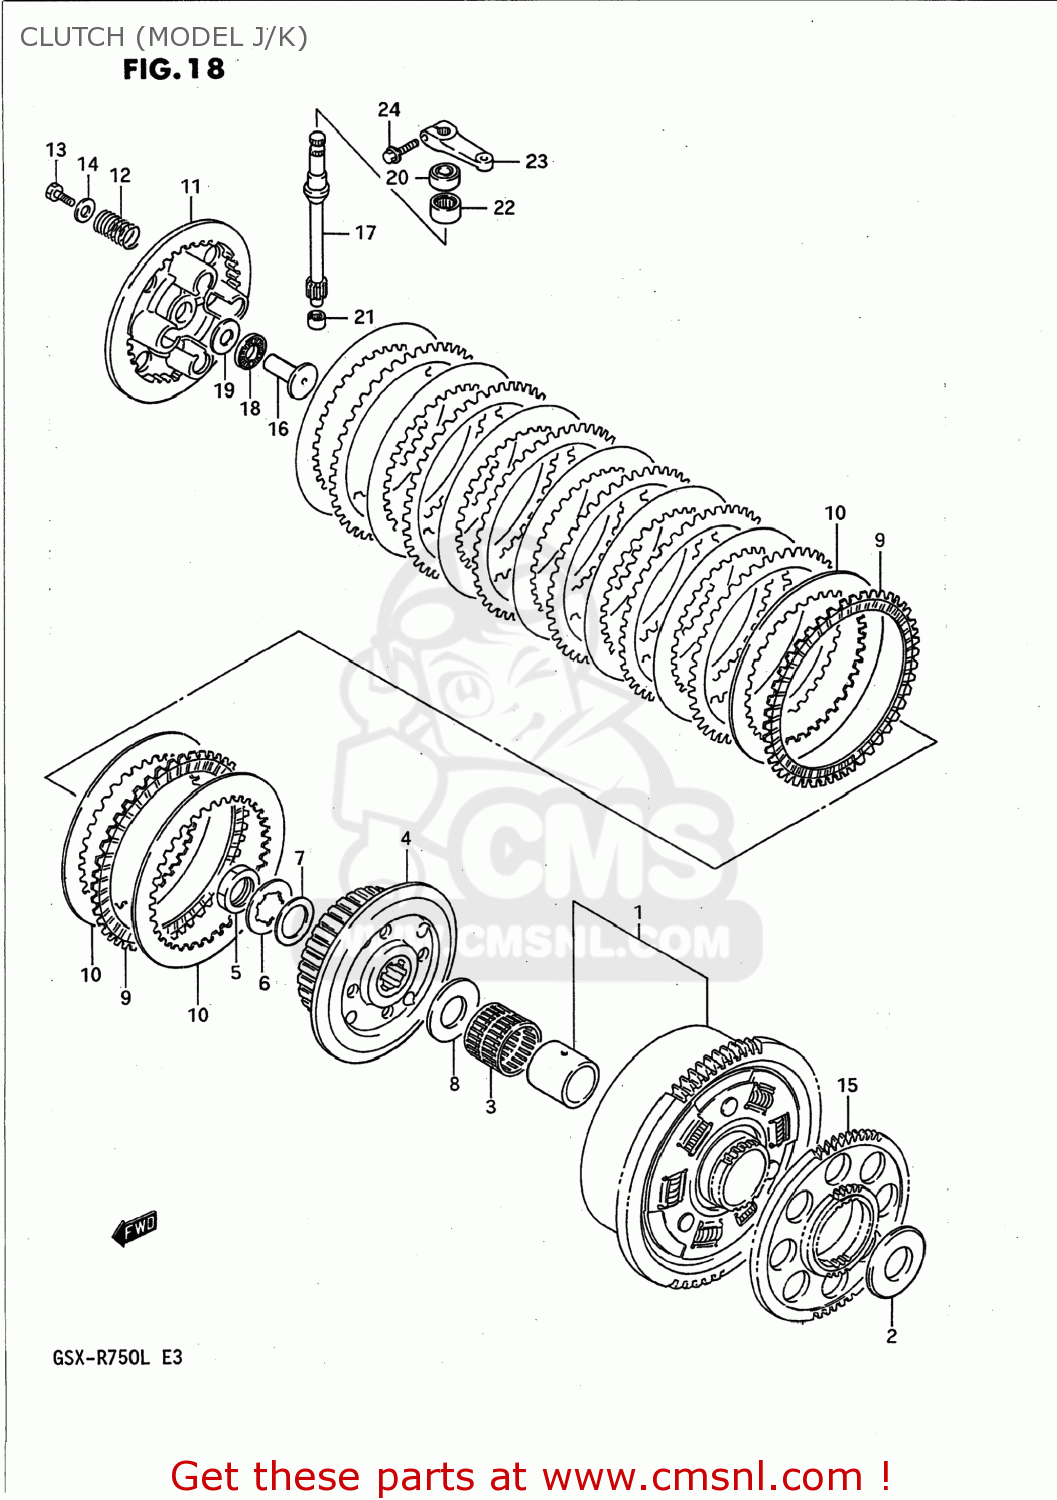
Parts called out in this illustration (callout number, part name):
1	GEAR ASSEMBLY,PRIMARY DRIVE
2	WASHER(25X54X2.5)
3	BEARING(35X40X35.8)
4	HUB,CLUTCH SLEEVE
5	NUT
6	WASHER,LOCK
7	WASHER
8	WASHER(25X50X2.5)
9	PLATE,CLUTCH DRIVE (NAS)
10	PLATE,CLUTCH DRIVEN (NAS)
11	DISC,CLUTCH PRESSURE
12	SPRING
13	BOLT
14	WASHER
15	GEAR,GENERATOR DRIVE
16	RACK,CLUTCH RELEASE
17	PINION,CLUTCH RELEASE
18	BEARING(15X28X2)
19	WASHER
20	OIL SEAL
21	BEARING 10X14X10
22	BEARING(15X22X12)
23	ARM,CLUTCH RELEASE
24	BOLT
